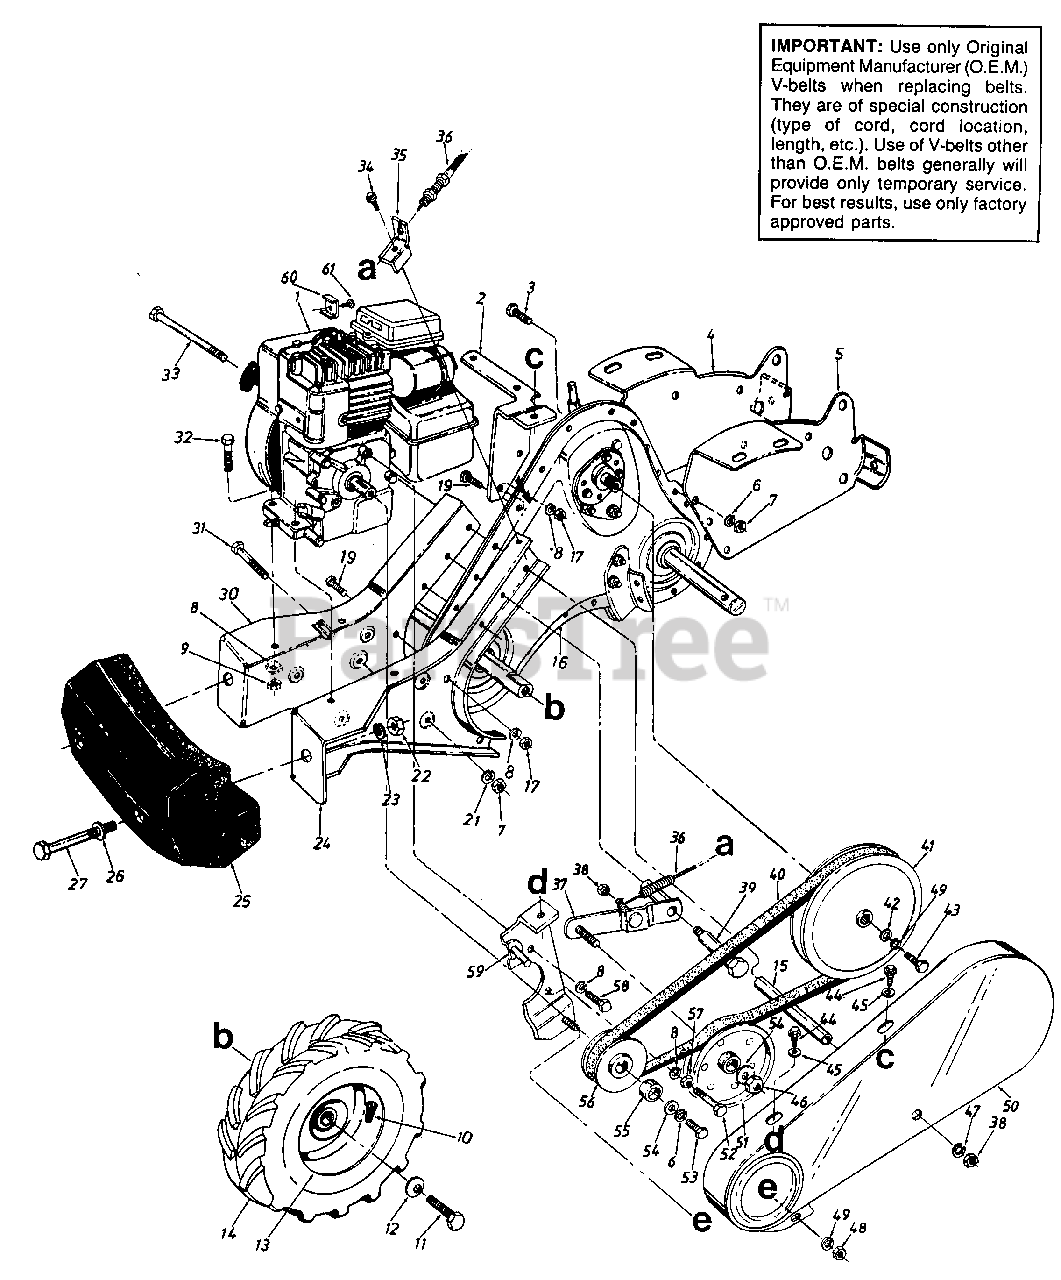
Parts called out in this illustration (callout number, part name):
7	NUT-HEX 3/8-16
8	WASHER-LOCK-5/16
9	NUT-HEX 5/16-18
10	VALVE-TUBELESS AIR
11	SCREW-HEX 5/16-24 X .62
12	WASHER-BELL .337 X .867 X .057
13	WHEEL RIM
14	WHEEL ASSY W/TIRE-LH
16	GEAR CASE ASSY
17	NUT-HEX 5/16-18
19	SCREW-HEX 5/16-18 X .75
21	WASHER-HDL 3/8
22	NUT-HEX 1/2-13
23	WASHER-LOCK-1/2
26	WASHER-FL
27	BOLT-HEX 1/2-13X5.0
32	SCREW-HEX 5/16-18 X 1.50
33	SCREW-HEX
34	SCREW-HEX WASH HD 5/16-18
36	CABLE-CLUTCH CONTROL
39	SCREW-SHLD
40	BELT-V 1/2 X 57.0
42	WASHER-FL
43	SCREW-HEX 1/4-28 X .75
44	SCREW-HEX WASH SF TAPP
45	WASHER-FL
46	NUT-HEX CENTER JAM 3/8-24
47	WASHER-FL-.344 ID X 1.12 OD X .063
48	NUT-HEX 1/4-20
49	LOCK WASHER 1/4 DIA
51	PULLEY-IDLER
52	SCREW-HEX 5/16-24 X 1.75
53	BOLT-3/8 NF X 1"GR5
54	WASHER-FL-.385 X 1.00 X .135
56	PULLEY HALF-ENGINE
57	NUT-5/16-24
58	SCREW-HEX 5/16-24 X .62
61	SCREW-HEX SEMS #10-32
